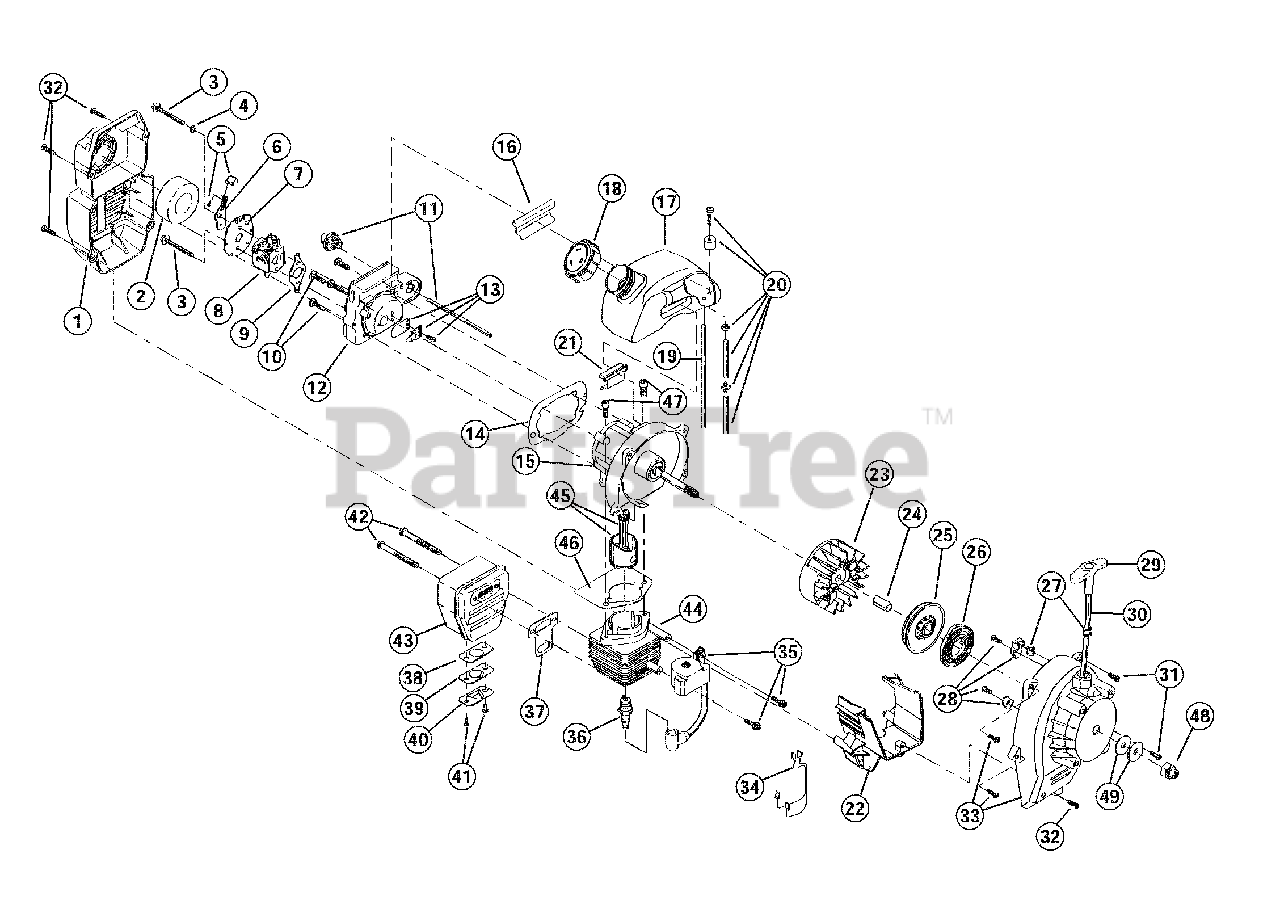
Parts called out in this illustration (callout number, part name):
1	Air Cleaner/Muffler Cover Assembly
2	Air Cleaner Filter
3	Carburetor Mounting Screw
4	Wavey Washer
5	Choke Knob and Screw
6	Choke Lever Assembly
7	Choke Lever and Plate
8	Carburetor Assembly
9	Carburetor Gasket
10	Carb Mount Screw
11	Primer and Hose Assembly
12	Carb Mount Assembly
13	Reed Assembly
14	Carburetor Mount Gasket
15	Crank Case Service Assembly
16	Rear Mounting Pad
17	Fuel Tank Assembly
18	Fuel Cap Assembly
19	Fuel Return Line
20	Fuel Line Assembly
21	Front Mounting Pad
22	Shroud Extension
23	Flywheel Assembly
24	Spacer
25	Recoil Pulley
26	Recoil Spring
27	Rope Guide
28	Pulley Retainer Assembly
29	Pull Handle
31	Housing Screw
32	Cover Screw
33	Starter Housing Assembly
34	Wire Lead Assembly
35	Module Assembly
36	Spark Plug
37	Exhaust Gasket
38	Spark Arrestor Screen
39	Exhaust Hood Diverter
42	Muffler Mounting Bolt Assembly
43	Muffler Assembly
44	Cylinder Assembly
45	Piston and Rod Assembly
46	Cylinder Gasket
47	Cylinder Bolt
48	Crankshaft Extension
49	Washer
